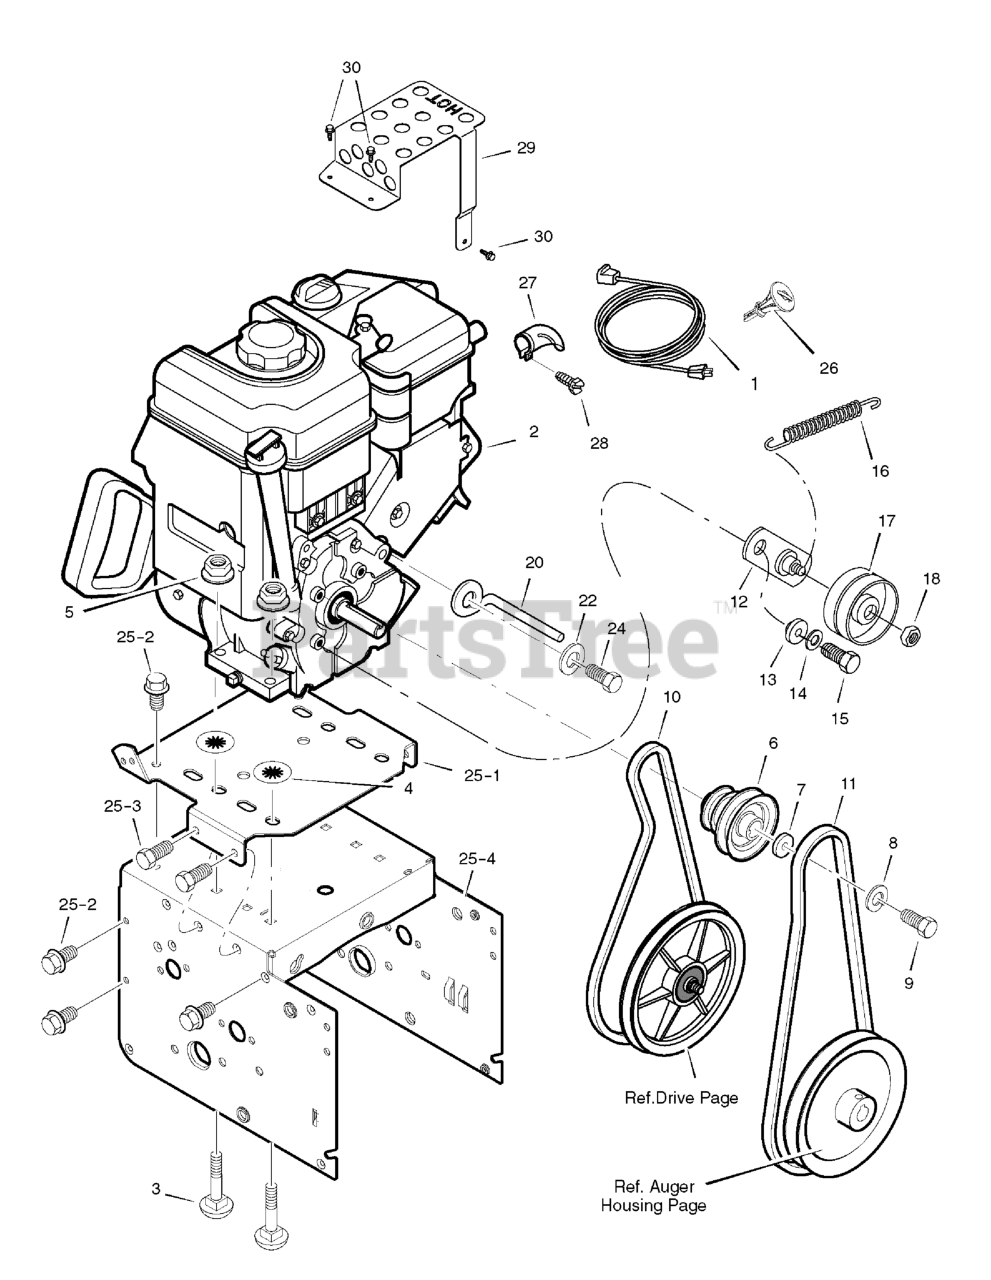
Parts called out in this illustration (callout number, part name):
1	CORD, Electric, 10FT. 110V
2	ENGINE
3	BOLT, Carriage
4	RETAINER, Push
5	NUT
6	PULLEY, Engine
8	WASHER, Flat
9	BOLT, Hex 5/16-24 x 1
10	V-BELT, Drive, 4L
11	V-BELT, Auger, 3L
12	BRACKET ASSEMBLY, Idler
13	BUSHING, Idler Bracket
14	WASHER, Split
15	SCREW, 5/16-24 x 3/4
16	SPRING, Idler Traction Drive
17	PULLEY, Idler
18	NUT, Jam, 3/8 - 16
20	GUIDE, Rod Belt
22	WASHER
25	FRAME ASSEMBLY
25-1	PLATE, Engine
25-2	SCREW
26	KEY, Briggs Engine
27	DEFLECTOR, Muffler
29	HEAT SHIELD, Muffler
30	SCREW
